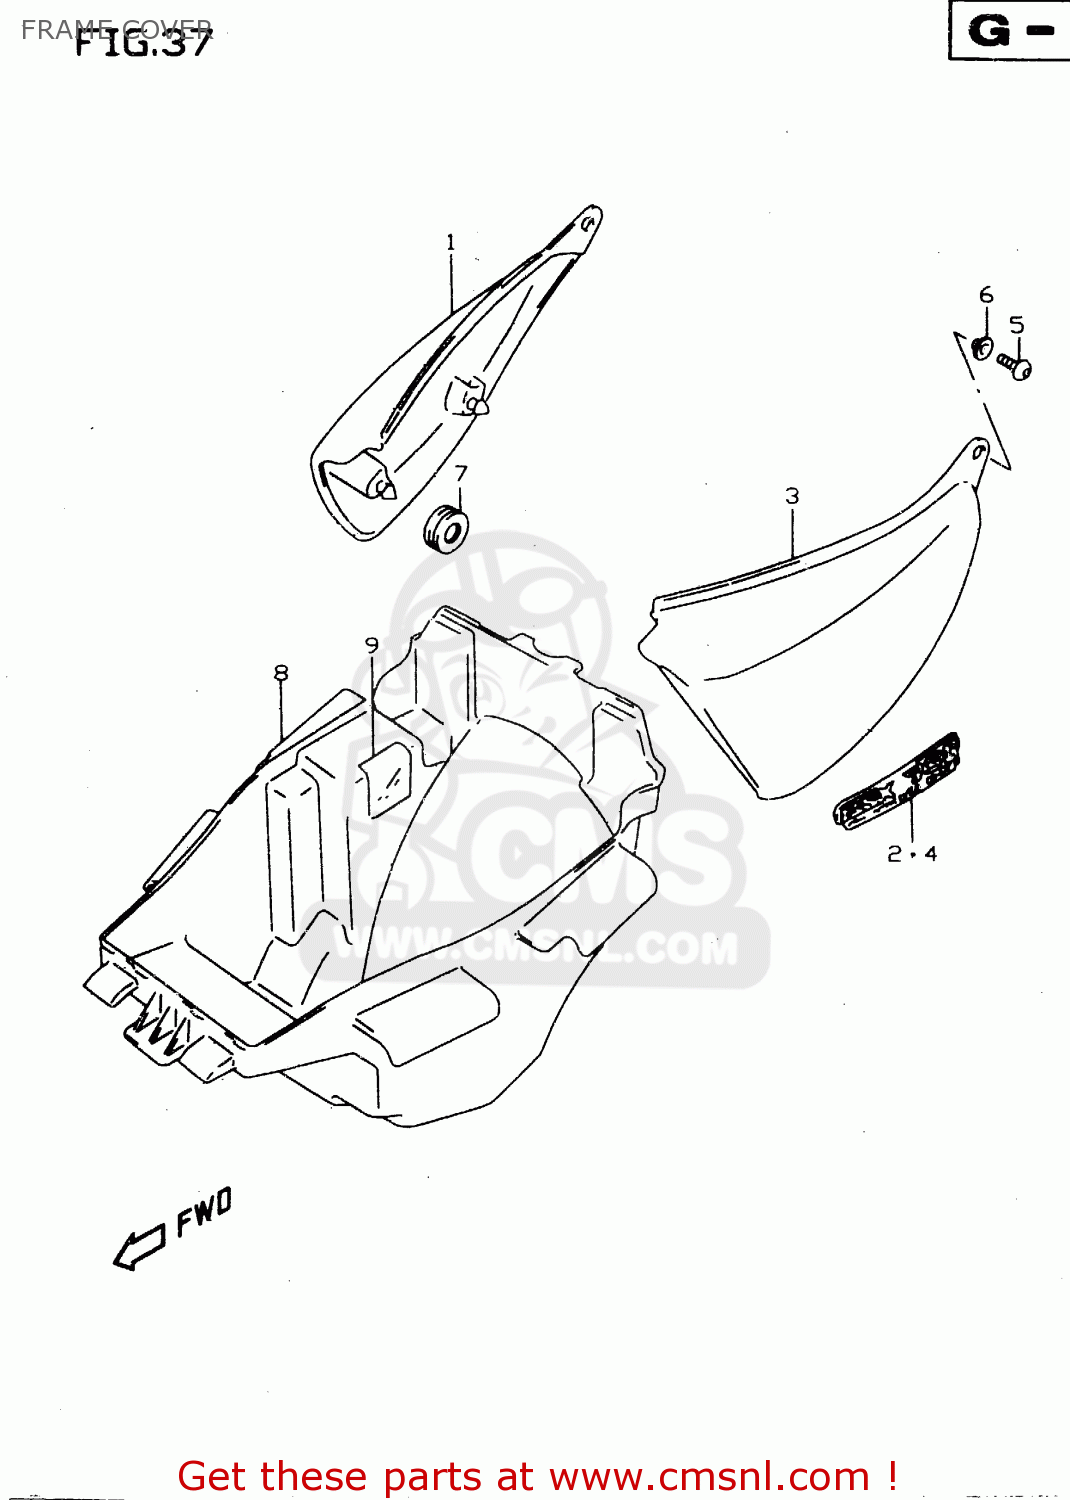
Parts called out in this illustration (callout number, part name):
1	COVER,FRAME,R(BLACK)
2	EMBLEM,FRAME COVER,R
3	COVER,FRAME,L(BLACK)
4	EMBLEM,FRAME,L
5	SCREW 6X12
6	WASHER
7	CUSHION
8	BODY,LUGGAGE B
9	PROTECTOR
